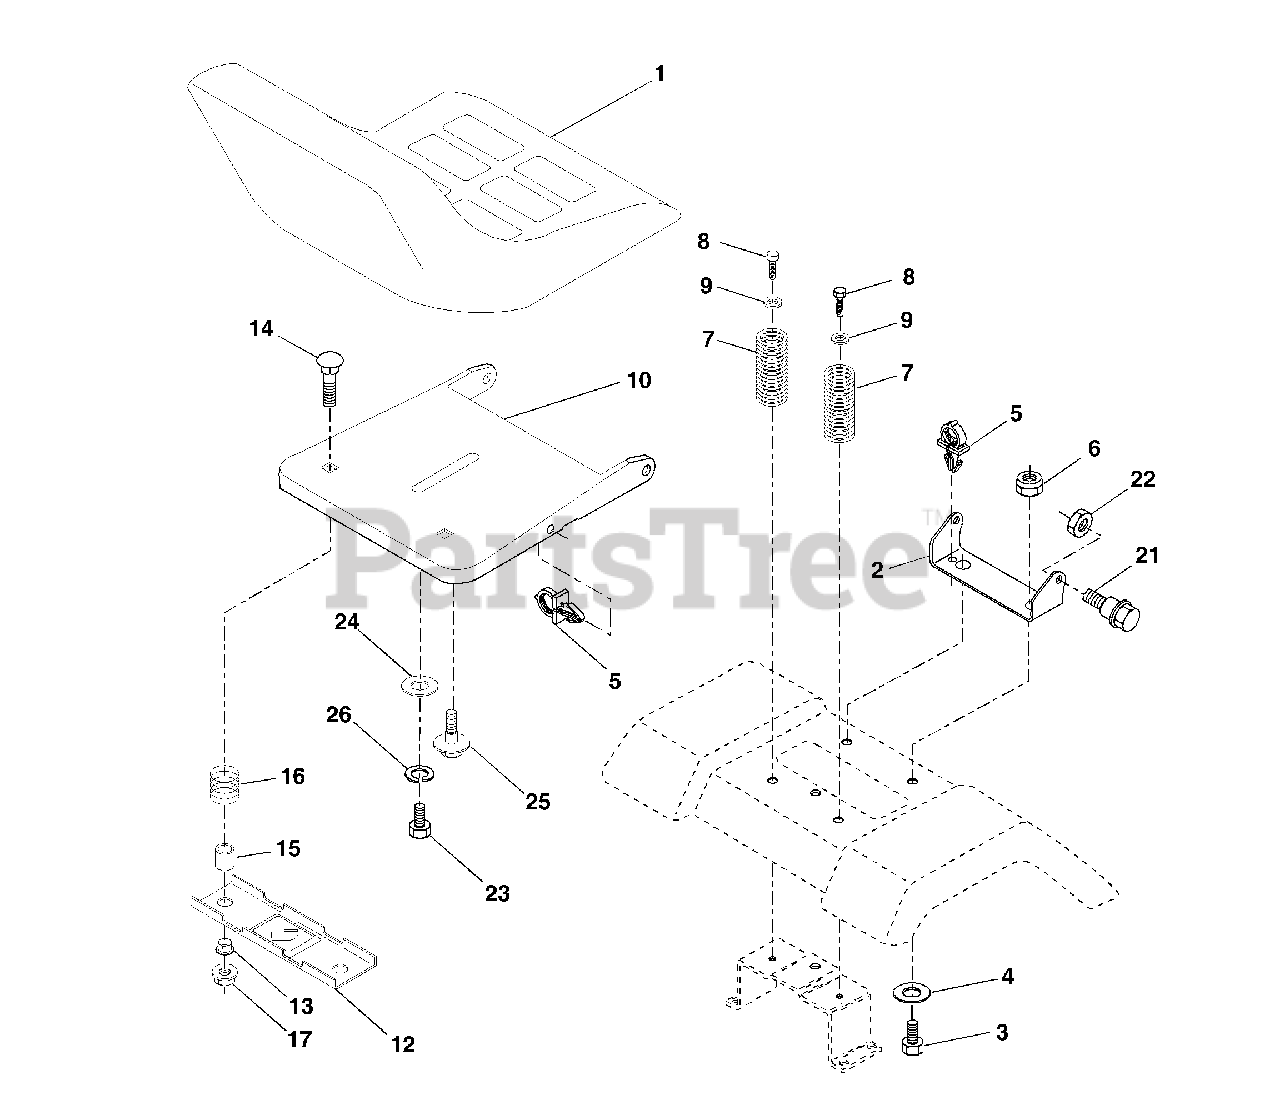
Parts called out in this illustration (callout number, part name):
2	Bracket Pnt Pivot Seat (blk )
3	Bolt
4	Washer 13/32 x 1 x 10 Ga
5	Clip Push-In Hinged
6	Nut
7	Spring Seat Cprsn 2 250 Blk Zi
8	Screw 3/8-16 x 1.5
9	Washer 13/32 x 1 x 14 Ga
10	Pan Pnt Seat (blk )
12	Bracket Pnt Mounting Switch
13	Bushing Snap Blk Nyl 50 Id
14	Bolt Rdhd Sht Nk 1/4-20 x 1-1/2
15	Spacer Split 28 x 96 Yel Zinc
16	Spring Cprsn 1 27 Blk Pnt
17	Nut Lock 1/4 Lge Flg Gr 5 Zinc
21	Bolt Shoulder 5/16-18 Unc Blkz-2A
22	Nut
23	Bolt Hex Blk
24	Washer 17/32 x 1-3/16 x 12 Ga
25	Bolt Shoulder 5/16-18 x 62
26	Lockwasher
